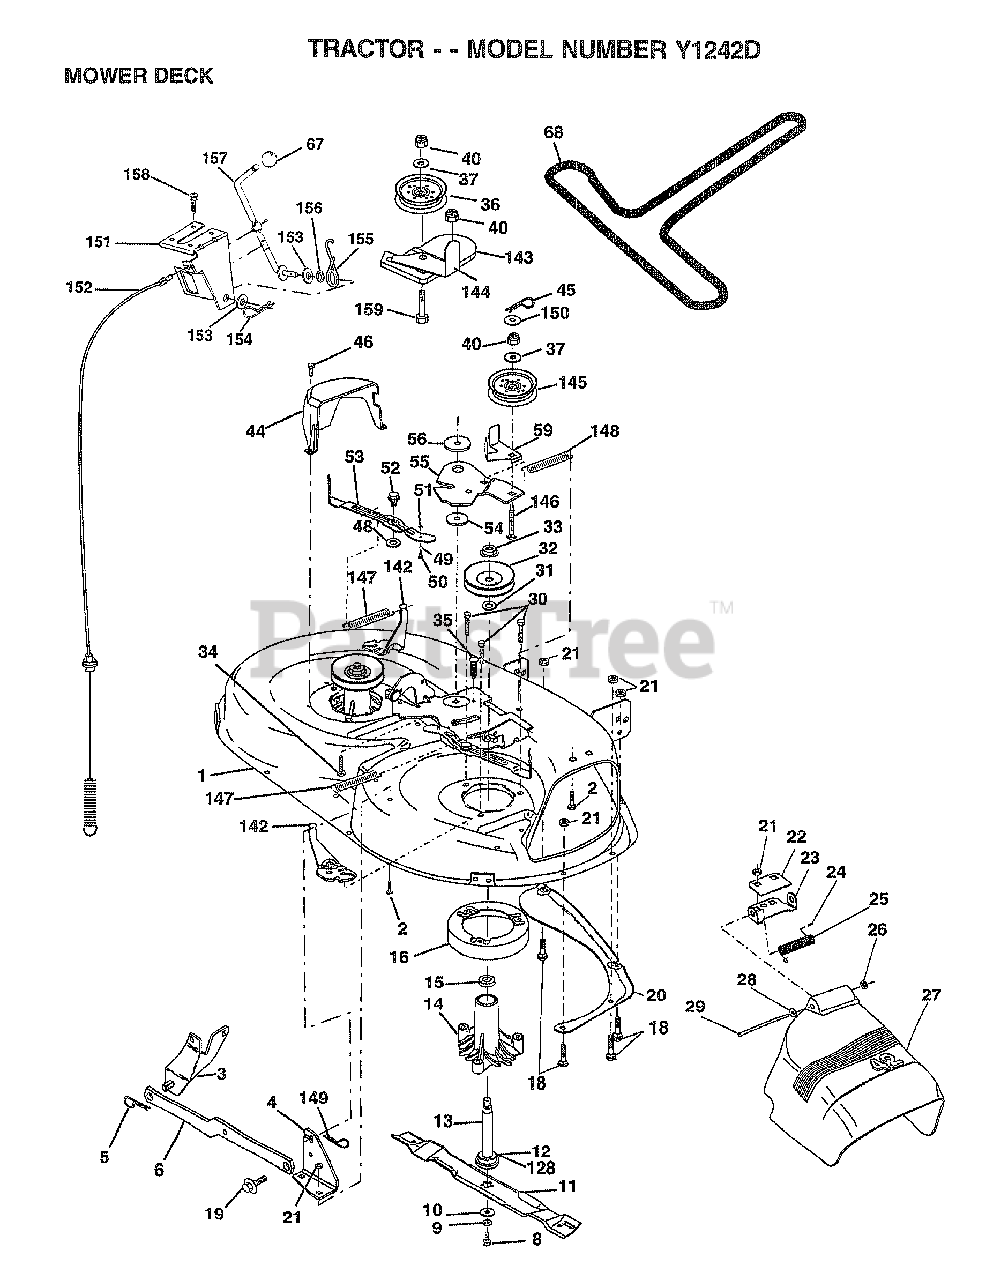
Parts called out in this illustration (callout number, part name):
1	MOWER DECK ASSY
2	BOLT
3	BRKT ASM SWAY BAR
4	BRACKET DECK
8	BLADE BOLT
10	WASHER.HARD.BLADE
11	"BLADE.42"" HIPERF"
12	BEARING.BALL
14	HSG ASM MANDREL
15	BEARING
16	STRIPPER RND MWR
18	BOLT
19	BOLT SHD 5/16-18
20	BAFFLE VORTEX 42
22	STIFFENER BRKT
23	DEFLECTOR BRKT
24	CAP-SLEEVE LT
25	SPRING TORSION
26	NUT PUSH M
27	SHIELD DEFLECTOR 42''
28	WASHER
29	HINGE ROD
30	"SCREW-THD ROLL,WA"
31	WASHER
32	PULLEY.MANDREL.42
34	BOLT
35	XMAS TREE FASTNER
36	FLAT IDLER PULLEY
37	WASHER
44	GUARD MAND LH BLK
45	RETAINER M
46	SCREW.1/4-20X5/8
48	HARD SMALL WASHER
49	ROLLER ASM-CAM
50	SHOULDER BOLT
51	LOCKNUT
52	BOLT.SHLD.5/16-18
53	BRAKE PAD ARM ASM
54	HARDENED WASHER
55	ARM-IDLER
56	SPACER.RETAINER.MOWER
59	GUARD IDLER TUV
67	KNOB T(3/8 HOLE)
68	BELT-V.SEC.46.KEL
128	WASHER.FELT.
142	ARM SPRING BRAKE MOWER
143	BRACKET ARM IDLER
144	KEEPER BELT CLUTCH CABLE
145	PULLEY IDLER FLAT
146	BOLT
147	SPRING EXTENSION
148	SPRING RETURN IDLER
149	RETAINER SPRING
150	WASHER PM
151	BRKT CLUTCH CABLE
152	"CABLE.CLUTCH.42"""
153	WASHER FLAT
154	SPRING RETAINER
155	SPRING RETENTION LVR CLUTCH CAB
156	SPACER
157	ROD.CLUTCH.CABLE.3/8
158	SCREW LT
159	BOLT
